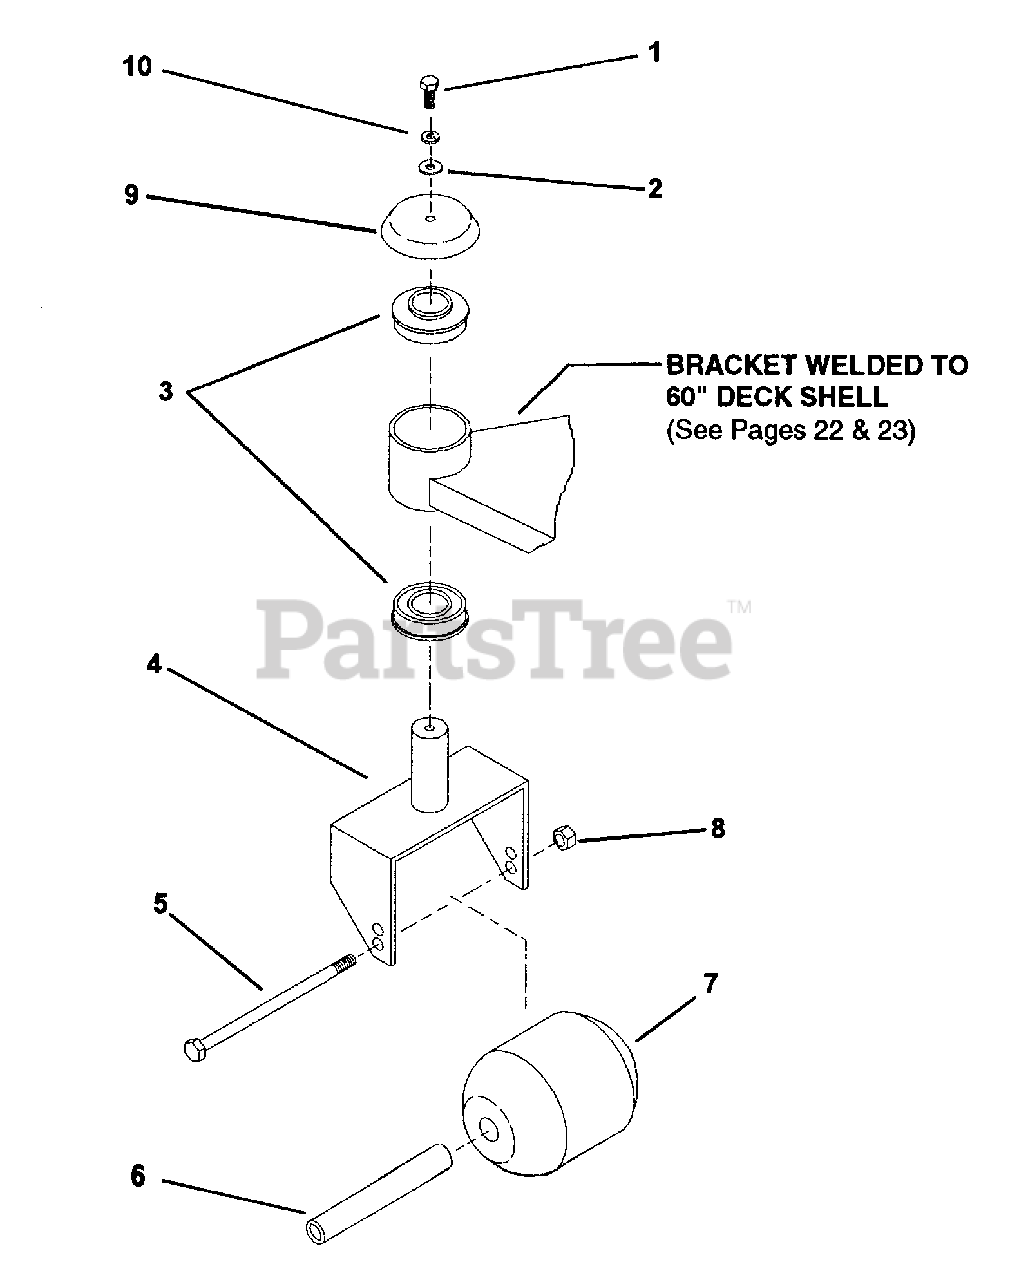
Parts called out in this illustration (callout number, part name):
1	BOLT, 1/4-20 X 3/4" GR. 5
2	WASHER, FLAT STD. 1/4"
3	BEARING, SPD SF-16-32 NO/COLLAR
4	SWIVEL YOKE WELDMENT
5	BOLT, 3/8-16 X 6" GR. 5
6	BUSHING
7	ROLLER, 3-3/4" X 4-13/16" LONG
8	NUT, 3/8-16 NYLOC
9	CAP, BEARING
10	LOCK WASHER, 1/4" SPLIT SPRING
